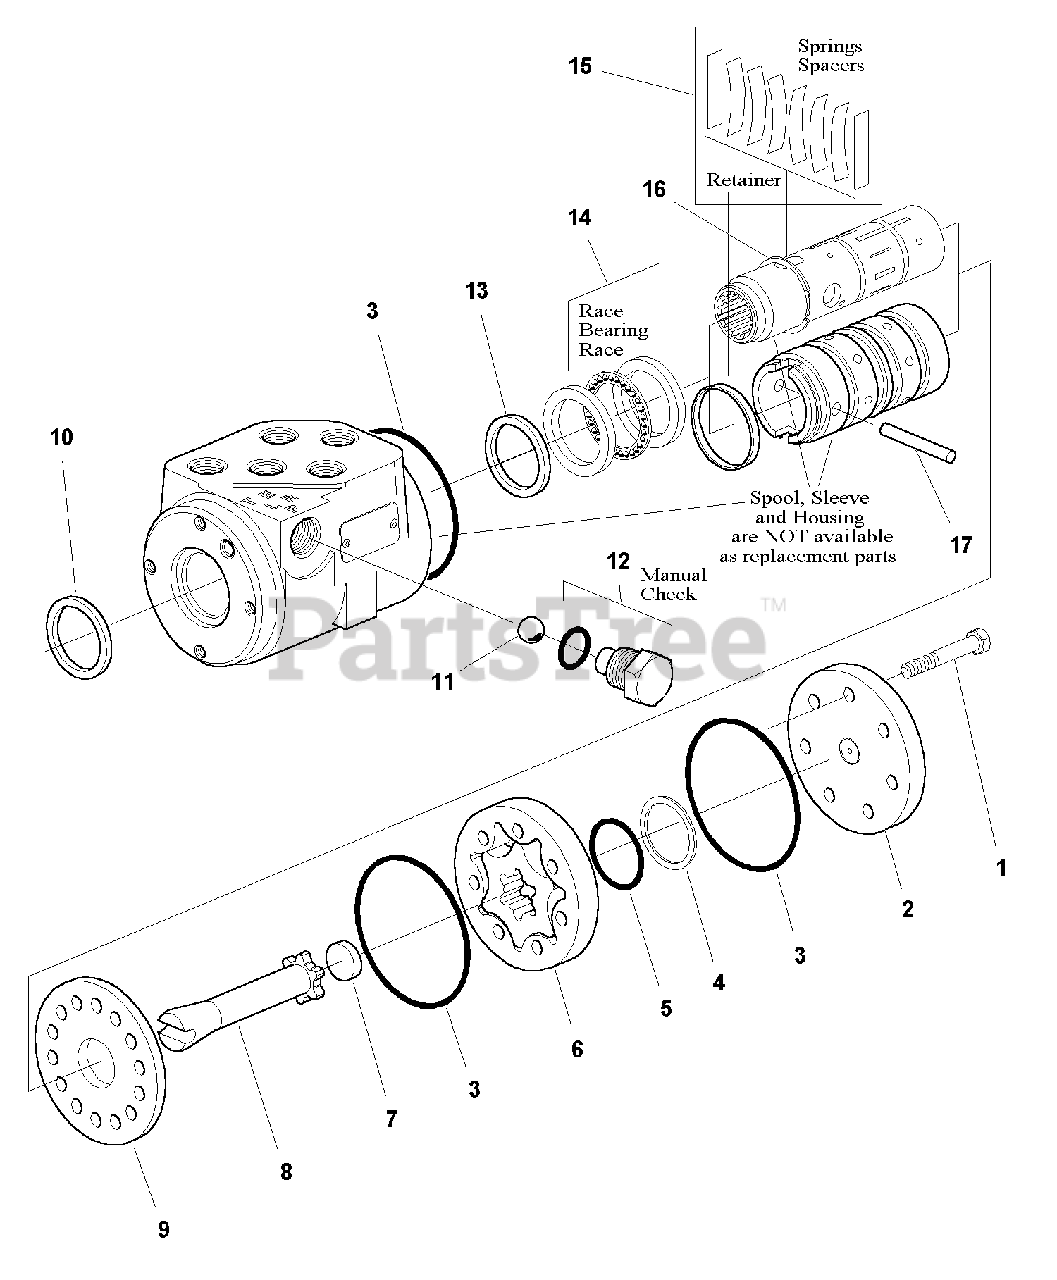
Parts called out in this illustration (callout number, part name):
3	SEAL, O-ring
8	DRIVE (Includes Sleeve & Spool)
9	PLATE, Wear
12	KIT, Plug & O-ring, (Includes Plug & O-ring Seal)
14	KIT, Bearing (Includes Bearing & Bearing Races)
15	KIT, Centering Spring (Includes Spring Spacer, Center Spring & Spring Retaining Ring)
16	RETAINING RING, External
18	SEAL KIT (Includes all seals & O-rings above)
